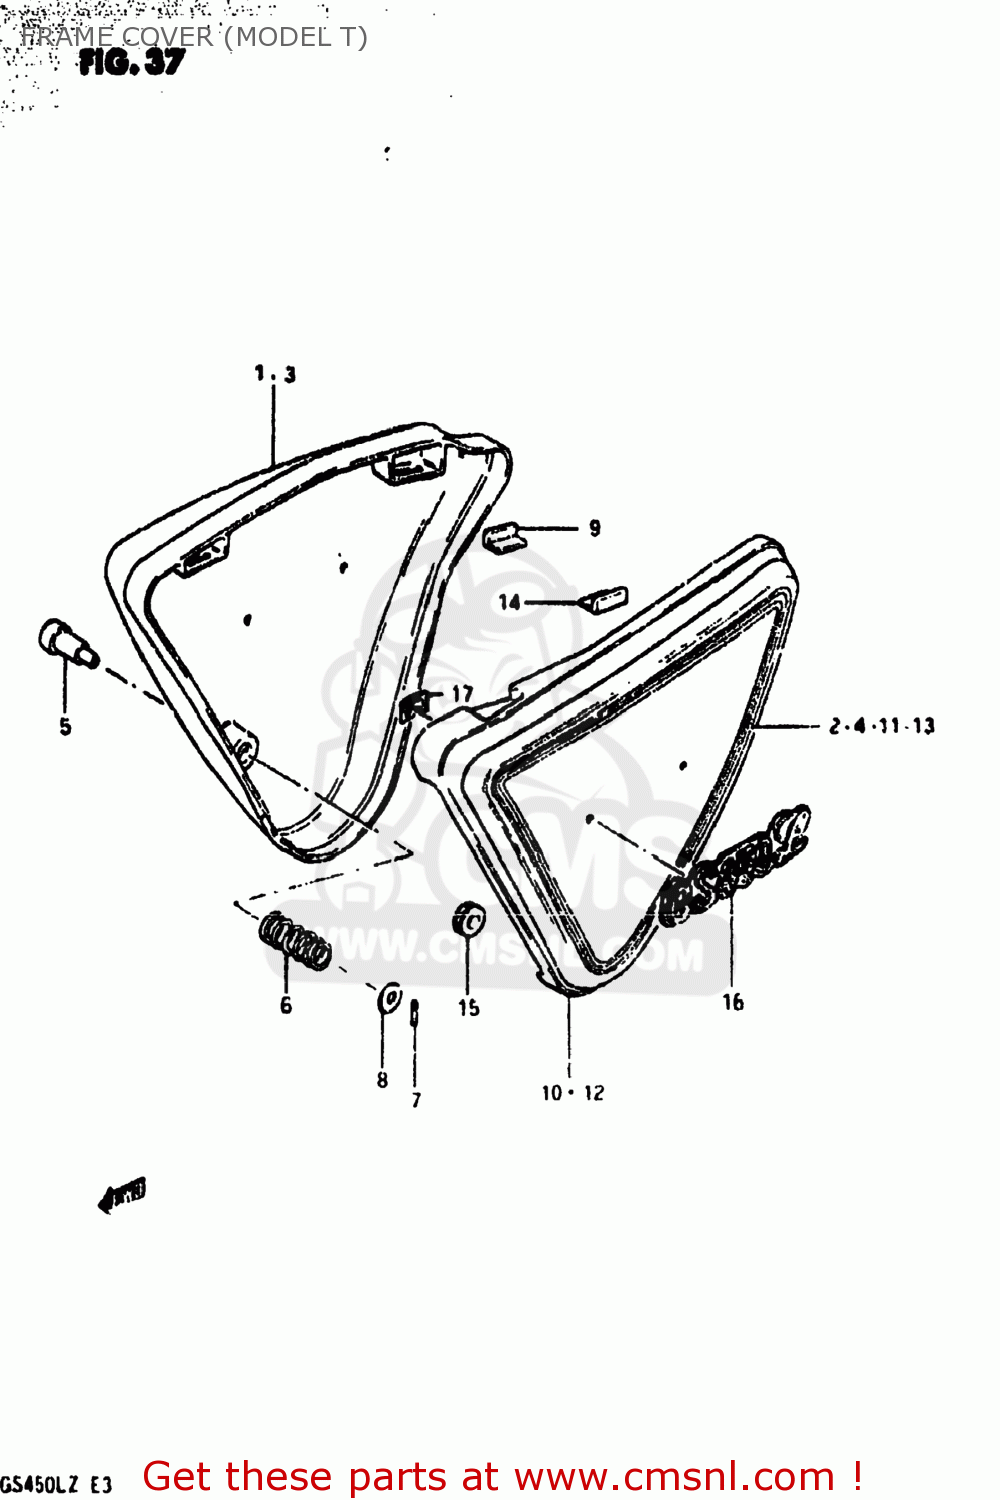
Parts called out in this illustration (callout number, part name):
1	COVER,FRAME,RIGHT
2	TAPE SET,FRAME COVER
3	COVER,FRAME,RIGHT
4	TAPE SET,FRAME COVER,RIGHT
5	KNOB,FRAME COVER,R
6	SPRING
7	PIN,SPRING(2.5X18)
8	WASHER
9	CUSHION,FRAME COVER
10	COVER,FRAME,LEFT
11	TAPE SET,FRAME COVER
12	COVER,FRAME,LEFT
13	TAPE SET,FRAME COVER,LEFT
14	CUSHION,FRAME COVER
15	CUSHION
16	EMBLEM
17	NUT
